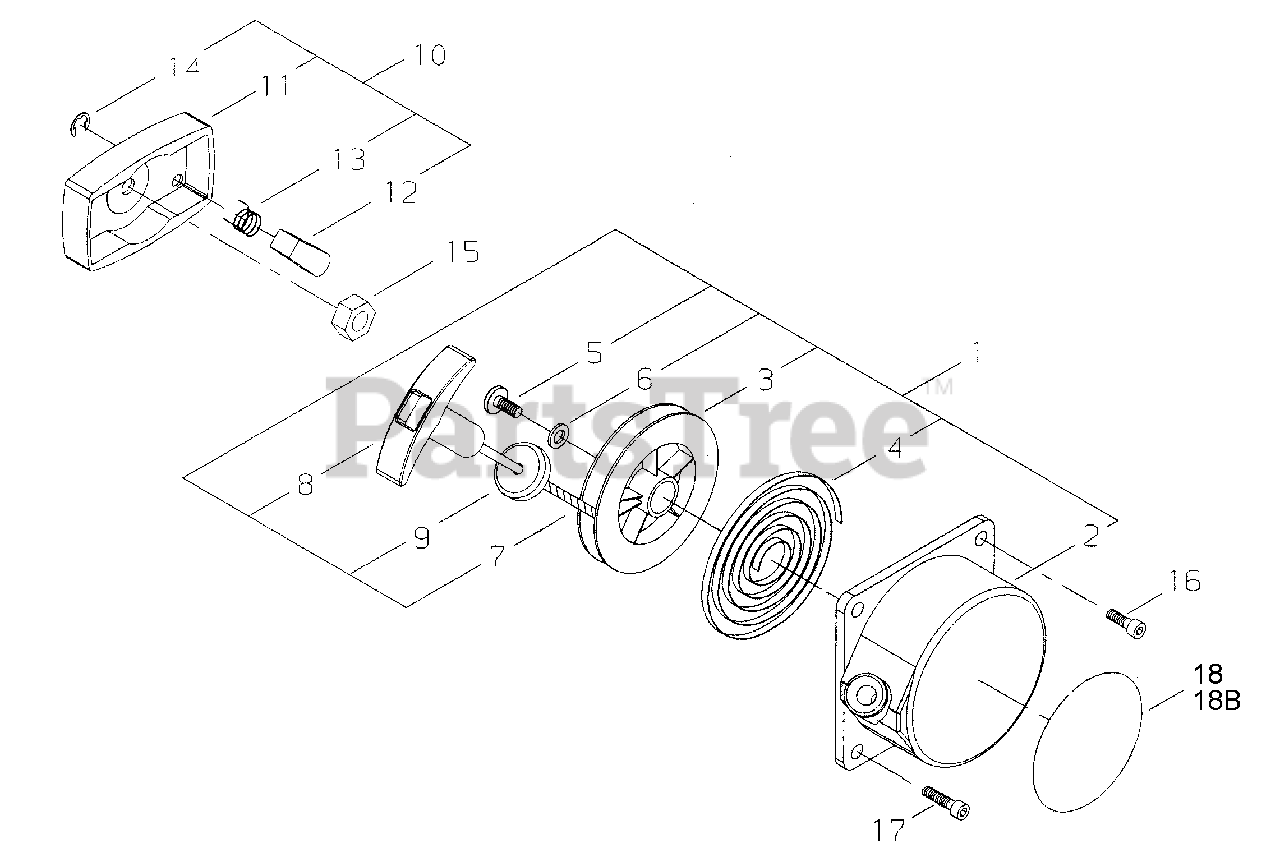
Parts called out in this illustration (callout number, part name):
1	STARTER ASSY
2	CASE, STARTER
3	REEL, ROPE
4	SPRING
5	SCREW
6	WASHER
7	ROPE
8	GRIP, STARTER
9	GUIDE, ROPE
10	STARTER PAWL ASSY
11	CASE, PAWL
12	PAWL, STARTER
13	SPRING, RETURN
14	RING, RETAINING
15	NUT
16	SCREW - 5X20
17	SCREW - 5X25
18	LABEL - MODEL
18B	LABEL - TRADE
